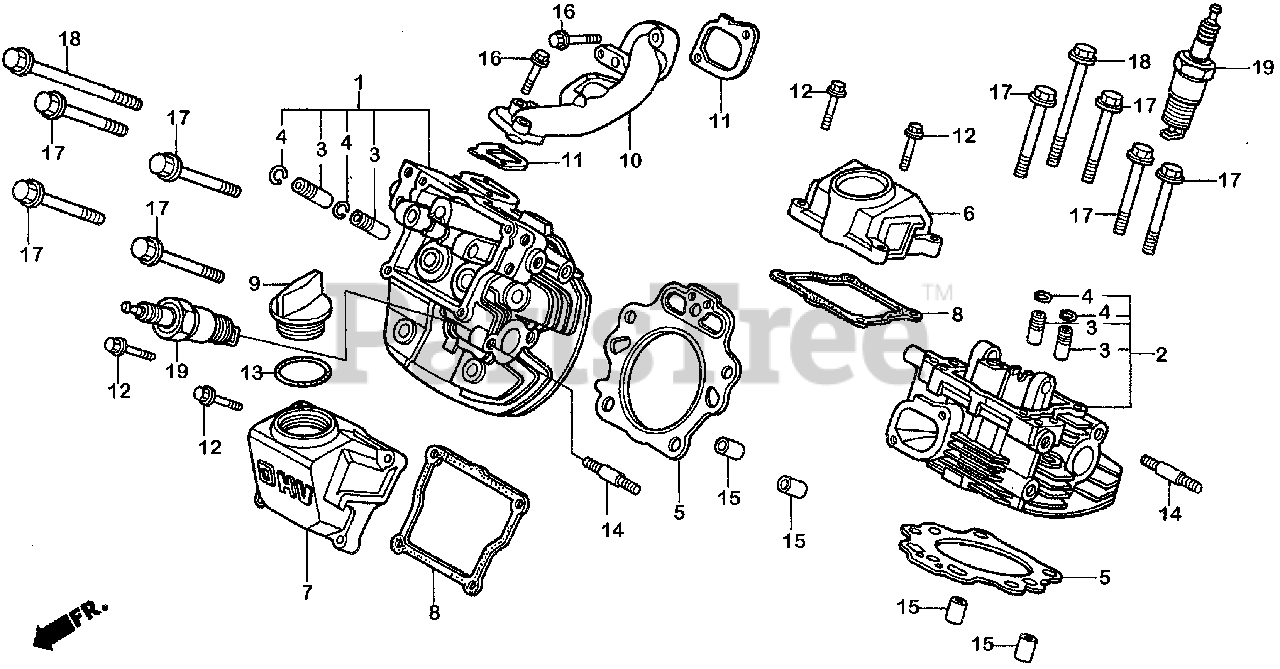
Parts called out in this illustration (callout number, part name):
1	CYLINDER HEAD, R.
2	CYLINDER HEAD (#2)
3	GUIDE, EX. VALVE (OS)
4	CLIP, VALVE GUIDE
5	GASKET, CYLINDER HEAD
6	COVER, HEAD (NOT AVAILABLE)
7	COVER, HEAD FILLER (NOT AVAILABLE)
8	GASKET, HEAD COVER
9	CAP, OIL
10	MANIFOLD, IN.
11	GASKET, IN. MANIFOLD
12	BOLT, FLANGE (6X25) (CT200)
12	BOLT, FLANGE (6X25) Use up to Engine SN 2056819.
13	O-RING (26X2.7)
14	BOLT, STUD (8X25)
15	PIN A, DOWEL (12X20)
16	BOLT, FLANGE (6X32)
17	BOLT, FLANGE (10X75)
18	BOLT, FLANGE (10X130)
19	SPARK PLUG (BPR6ES) (NGK)
